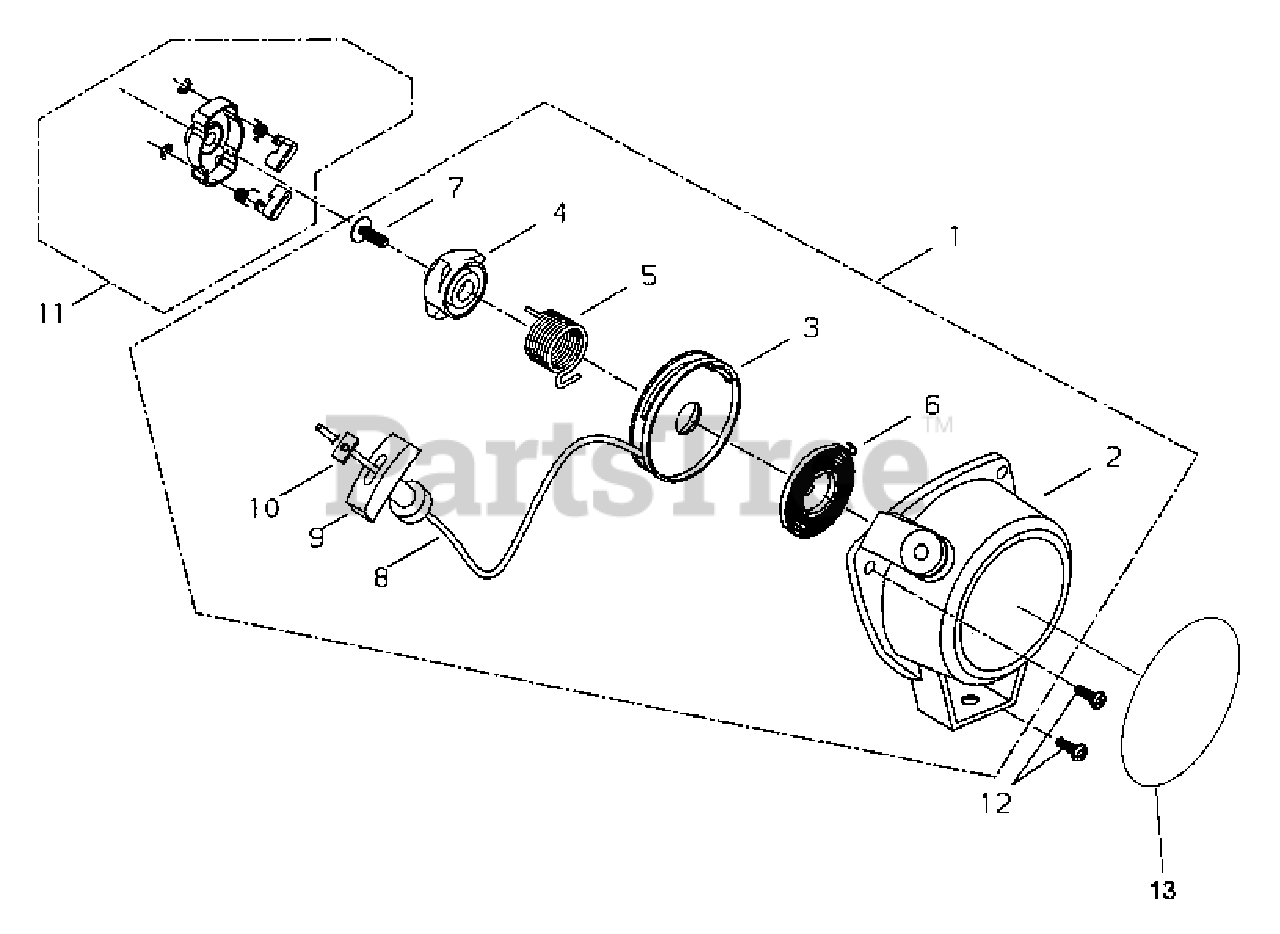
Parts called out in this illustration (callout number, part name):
1	STARTER ASSY
2	CASE, STARTER
3	REEL, ROPE
4	CAM
5	SPRING, TORSION
6	SPRING, RECOIL
7	SCREW 5
8	ROPE, STARTER
9	GRIP, STARTER
10	RETAINER, ROPE
11	PULLEY, STARTER
13	LABEL, RECOIL STARTER
